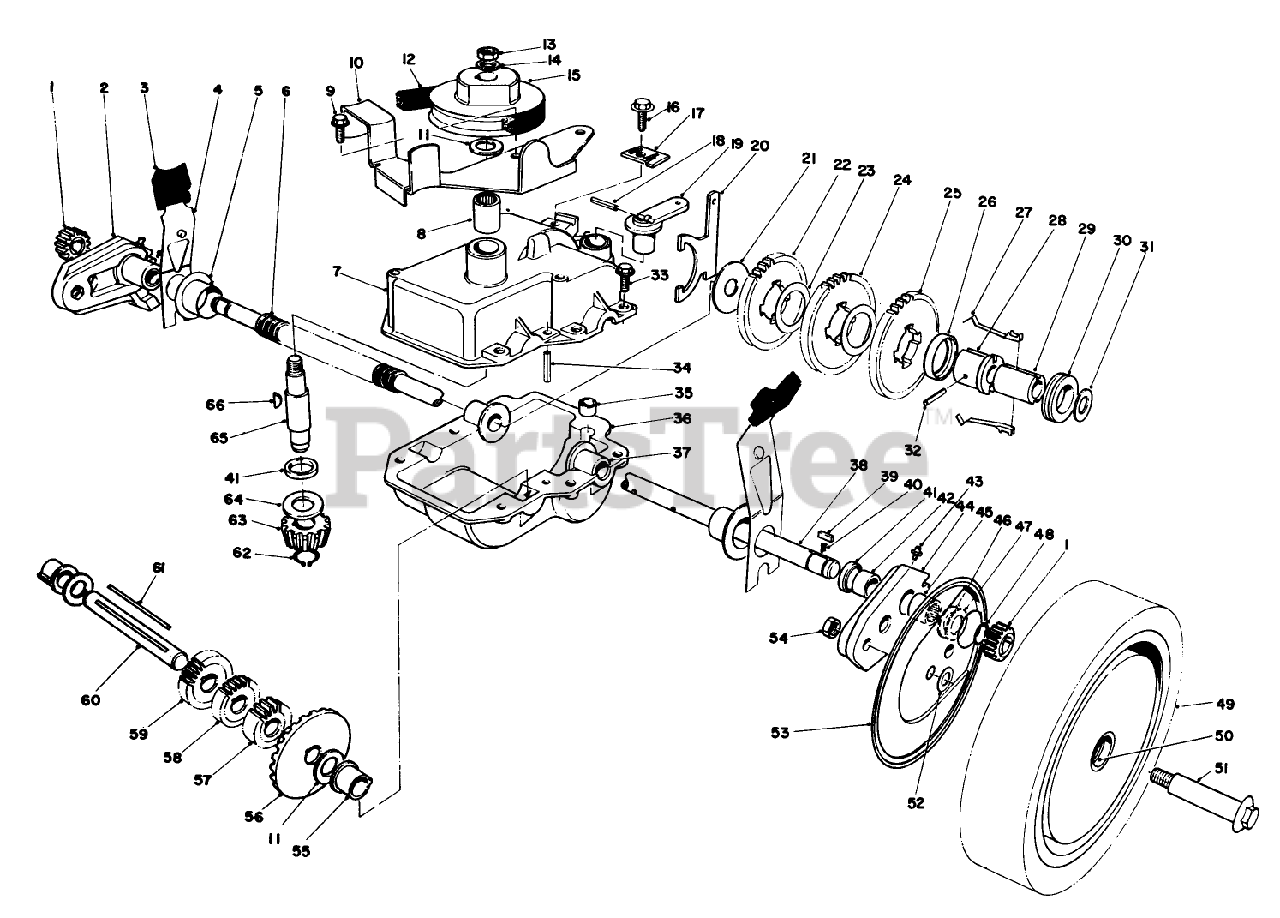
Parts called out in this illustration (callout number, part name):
1	GEAR-PINION
2	PIVOT ARM ASM RH
3	KNOB-ARM
4	SPRING ARM ASM SP
5	CAP-END
6	CONDUIT-CONVOLUTED, SPLIT
7	DISC PRC4
8	BEARING
9	SCREW
11	WASHER-THRUST
12	V-BELT
13	NUT-LOCK
14	WASHER-FLAT
15	PULLEY
16	SCREW-THD ROLL, HWH
18	PIN-SPRING
19	LEVER-SHIFT
21	WASHER
22	GEAR-38T
23	WASHER
24	GEAR-42T
27	KEY-SHIFT
29	SLEEVE
30	COLLAR-SHIFT
31	WASHER-PLAIN
33	SCREW-HWHTF
34	ROLL PIN 3/16 X 1 IN
35	BUSHING-YOKE
39	KEY RECTANGULAR
40	SPRING-COMPRESSION
42	BUSHING
43	FITTING-GREASE
47	WASHER-THRUST, OUTER
48	RING-RETAINING
50	BUSHING
51	WHEEL BOLT
52	WASHER
53	WHEEL COVER
54	NUT-LOCK
55	BUSHING
57	GEAR-12T
58	GEAR-14T
59	GEAR-18T
62	RING-RETAINING
63	PINION-BEVEL
64	WASHER-THRUST
66	KEY-WOODRUFF
